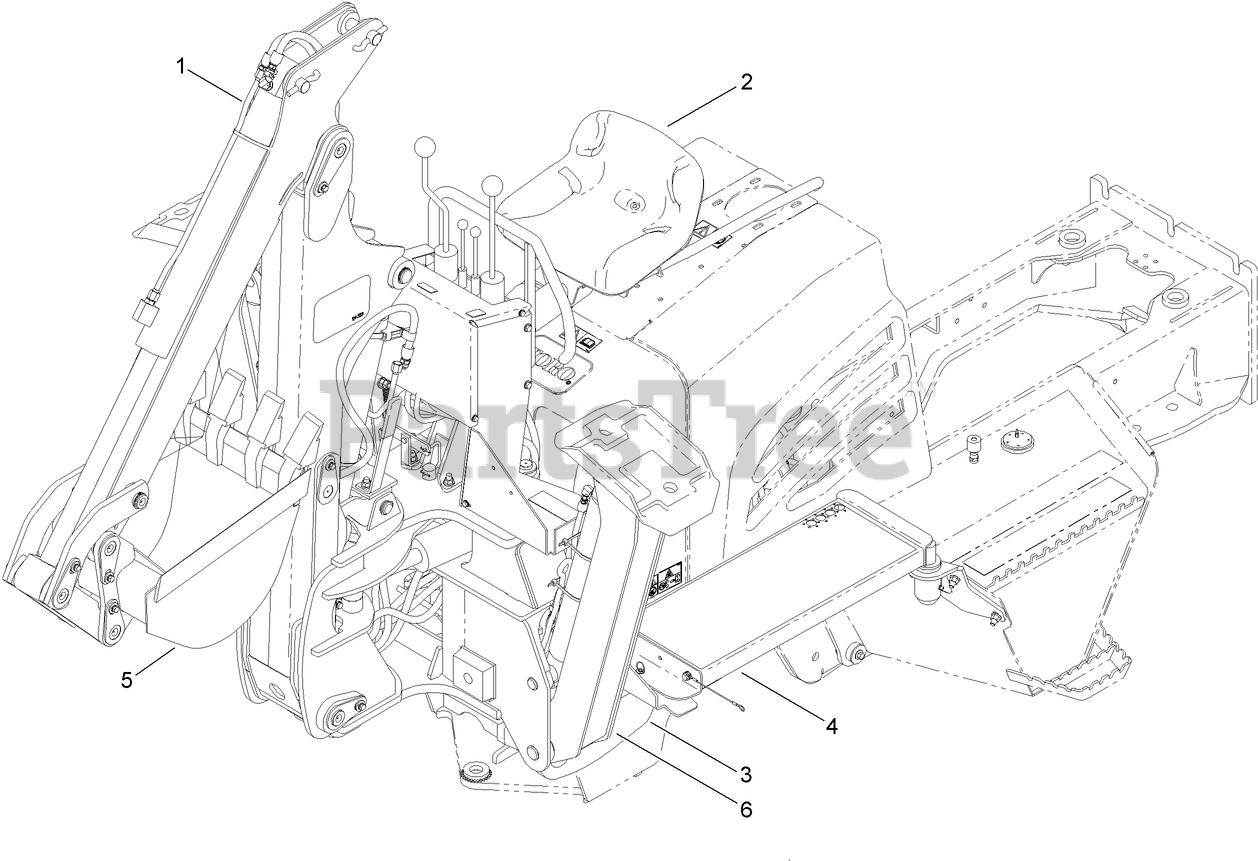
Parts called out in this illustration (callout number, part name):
1	BACKHOE ASM
2	ATTACH-SEAT/BUCKET KIT
3	ATTACH KIT
4	WALKWAY KIT
5	BUCKET-TRENCHING, 18IN
6	STABILIZER-WING TYPE KIT
